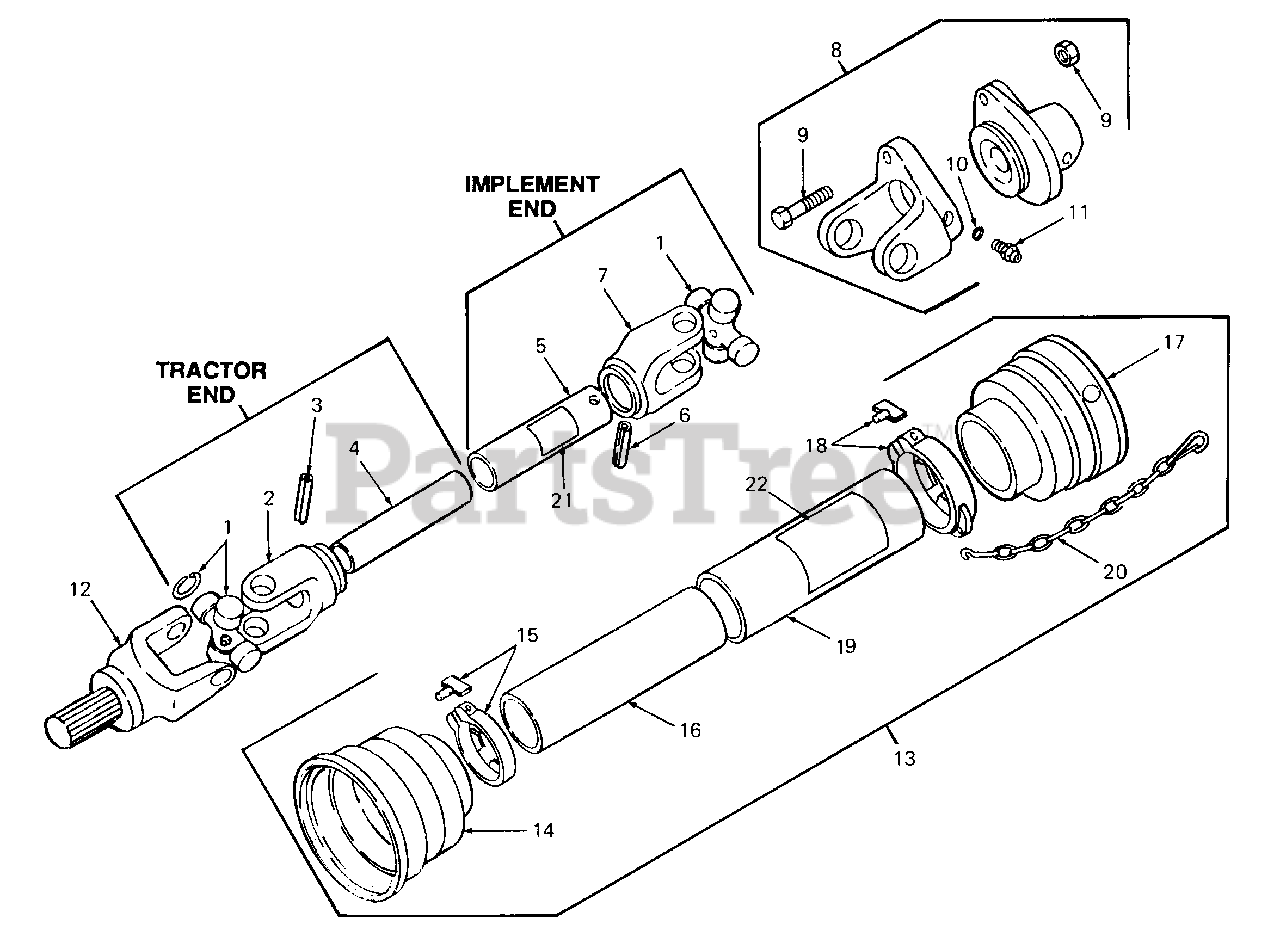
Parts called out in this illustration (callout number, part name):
1	Cross & Bearing
2	Yoke, Male Tube
3	Pin, Roll, M8 X 50
5	Tube, Female
6	Pin, Roll, M8 X 55
7	Yoke, Female Tube
8	Yoke Assy, Implement End w/Shear Bolt
9	Bolt, Shear, M6 X 40
10	Bearing, Ball
11	Fitting, Grease
12	Yoke, Spline. 1"-15
13	Shield, Complete
14	Guard, Inner Cone
15	Collar, Inner Locking
16	Shield, Male Tube
17	Guard, Outer Cone
18	Collar, Outer Locking
19	Shield, Female Tube
20	Chain, Safety
21	Decal, Danger Shield Missing
22	Decal, Danger Rotating Driveline
